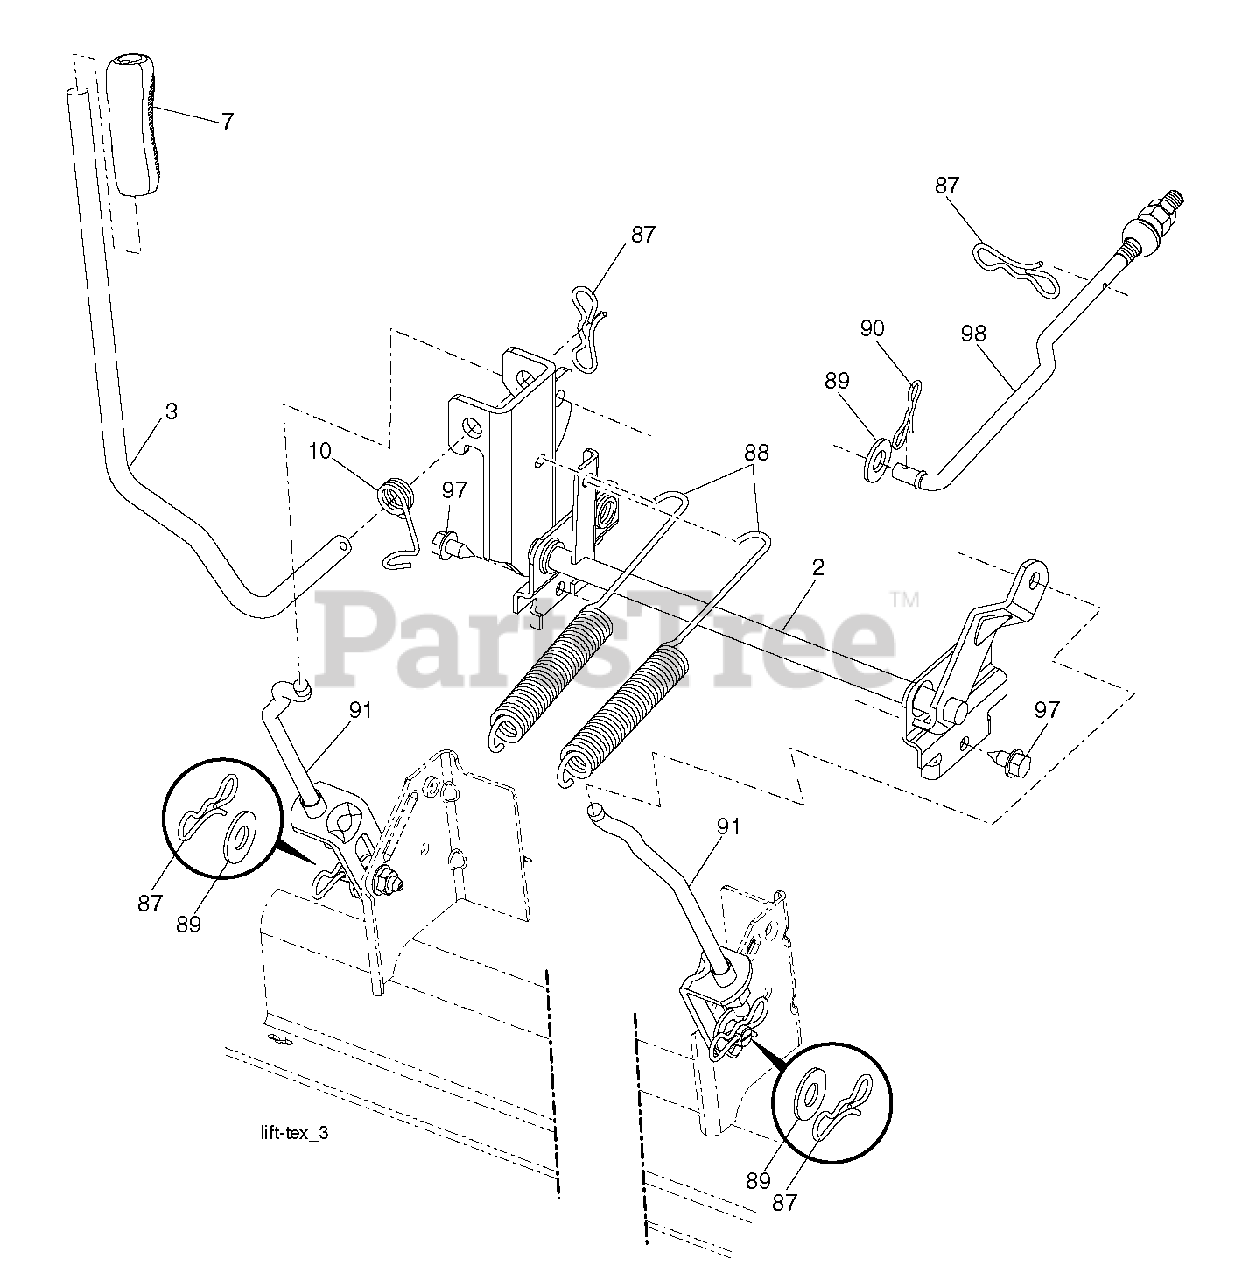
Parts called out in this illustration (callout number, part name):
2	SHAFT.ASM.CROSS.LIFT
3	LEVER.LIFT.HANDLE.LT
7	GRIP, LEVER
10	SPRING.TORSION.LIFT.HA
87	PIN.COTTER.7/16.BOW TI
88	SRPING.LIFT.ASSIST
89	WASHER.CLEAR.ZINC
90	PIN.COTTER.5/16.BOW TI
91	LINK.ASM.LIFT.54"TG
97	SCREW, 3/8-16X3/4
98	LINK.ASM.SUSP.FRONT.MWR.10.5
